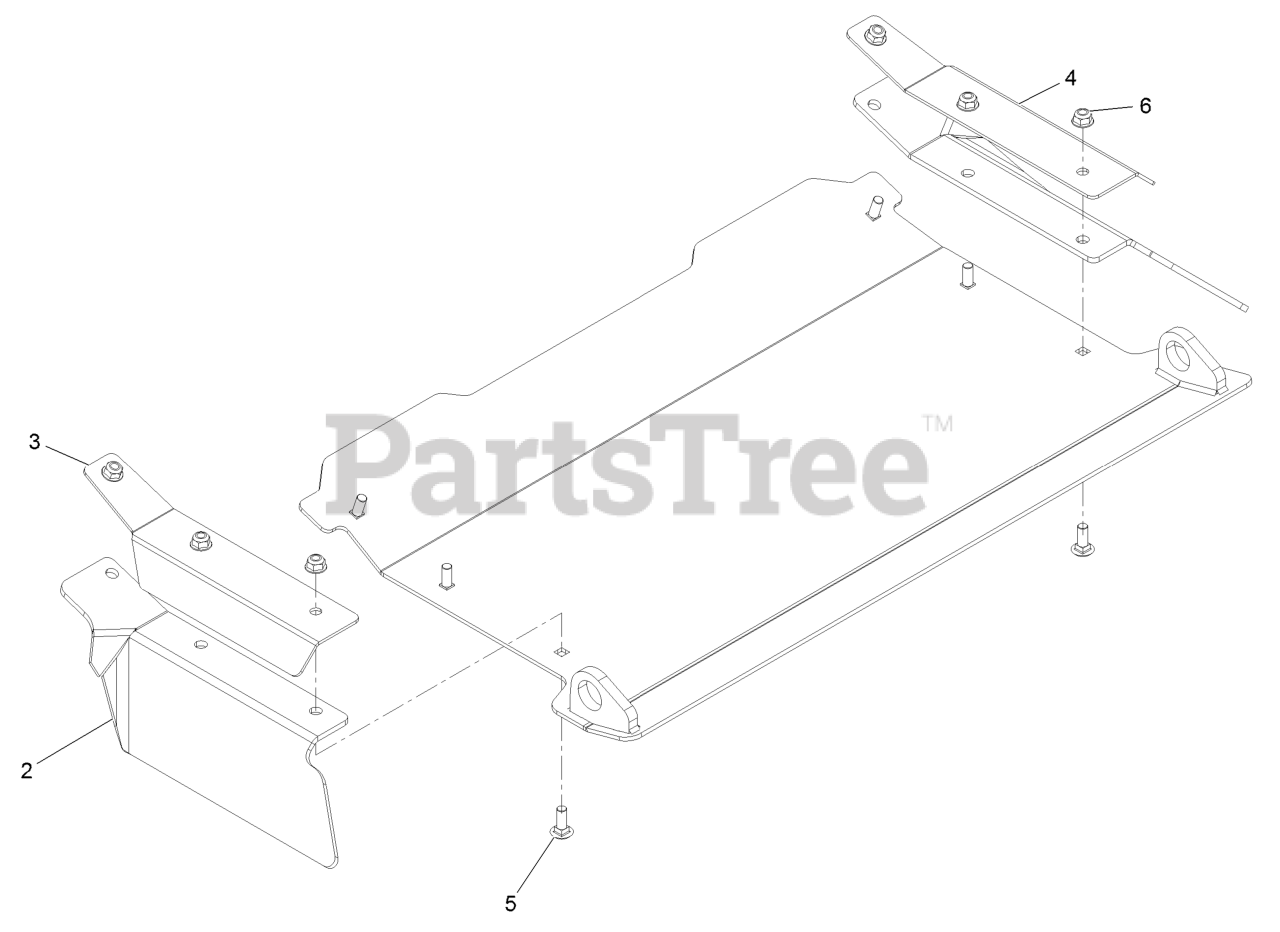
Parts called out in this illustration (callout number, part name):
2	FLAP-RUBBER
3	BRACKET-FLAP, LH
4	BRACKET-FLAP, RH
5	SCREW-CARR
6	NUT-HF, NI
